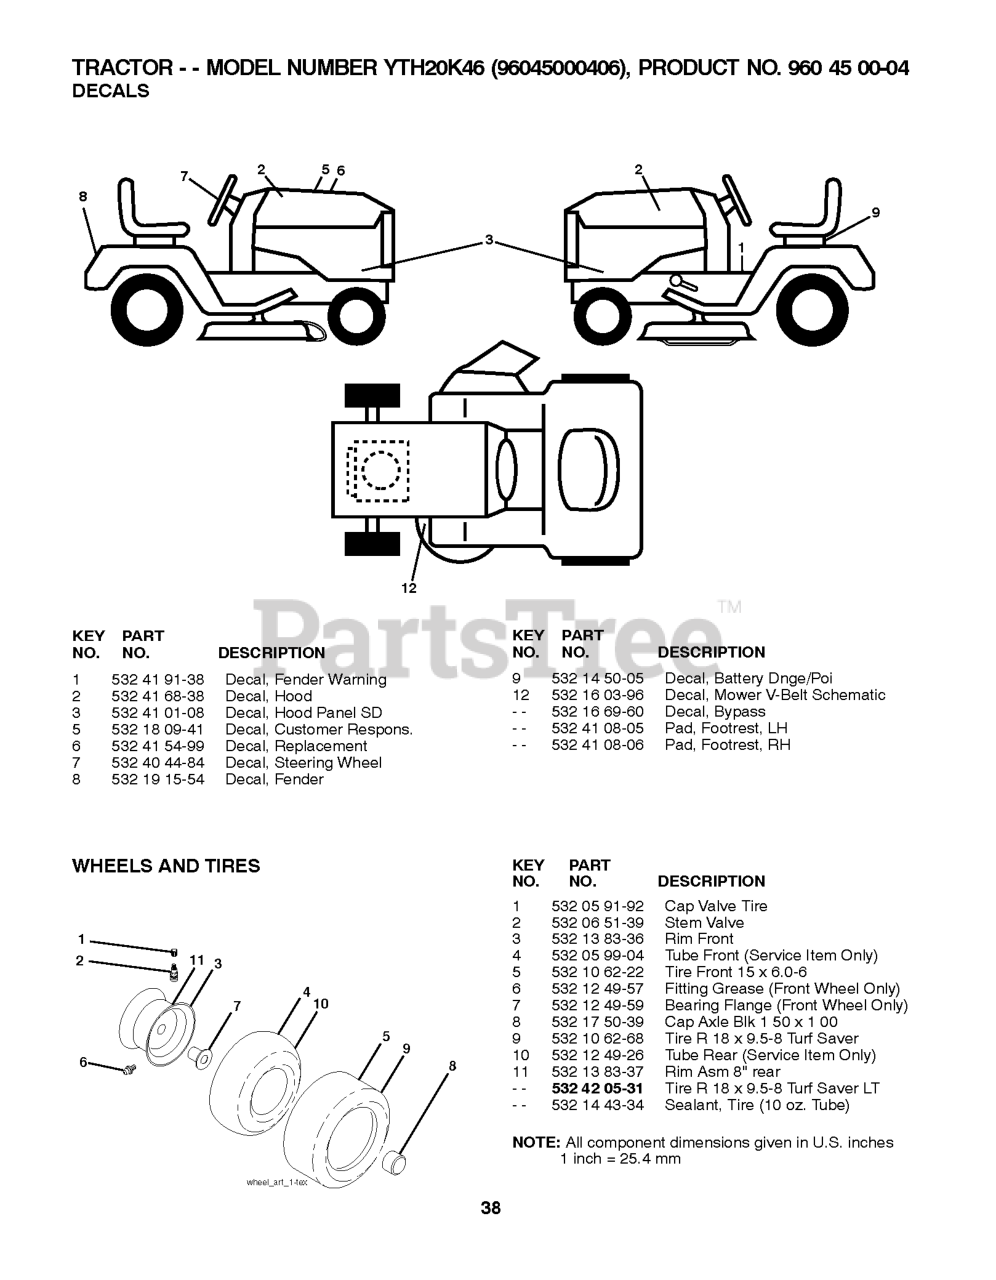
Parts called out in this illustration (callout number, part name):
1	DECAL.WARN.START.INSTRUCTIONS
2	DECAL.HOOD.LOGO.HUSQVARNA
3	DECAL, HOOD PANEL SD
5	DECAL HOOD CUST. RESP.
6	DECAL.RPL.KH.SV600.TLW.46"
7	DECAL.WHEEL.STRG.LGN.H
8	DECAL.FENDER
9	DECAL BTRY SYMBOLS
12	DECAL V BELT SCHEMATIC
